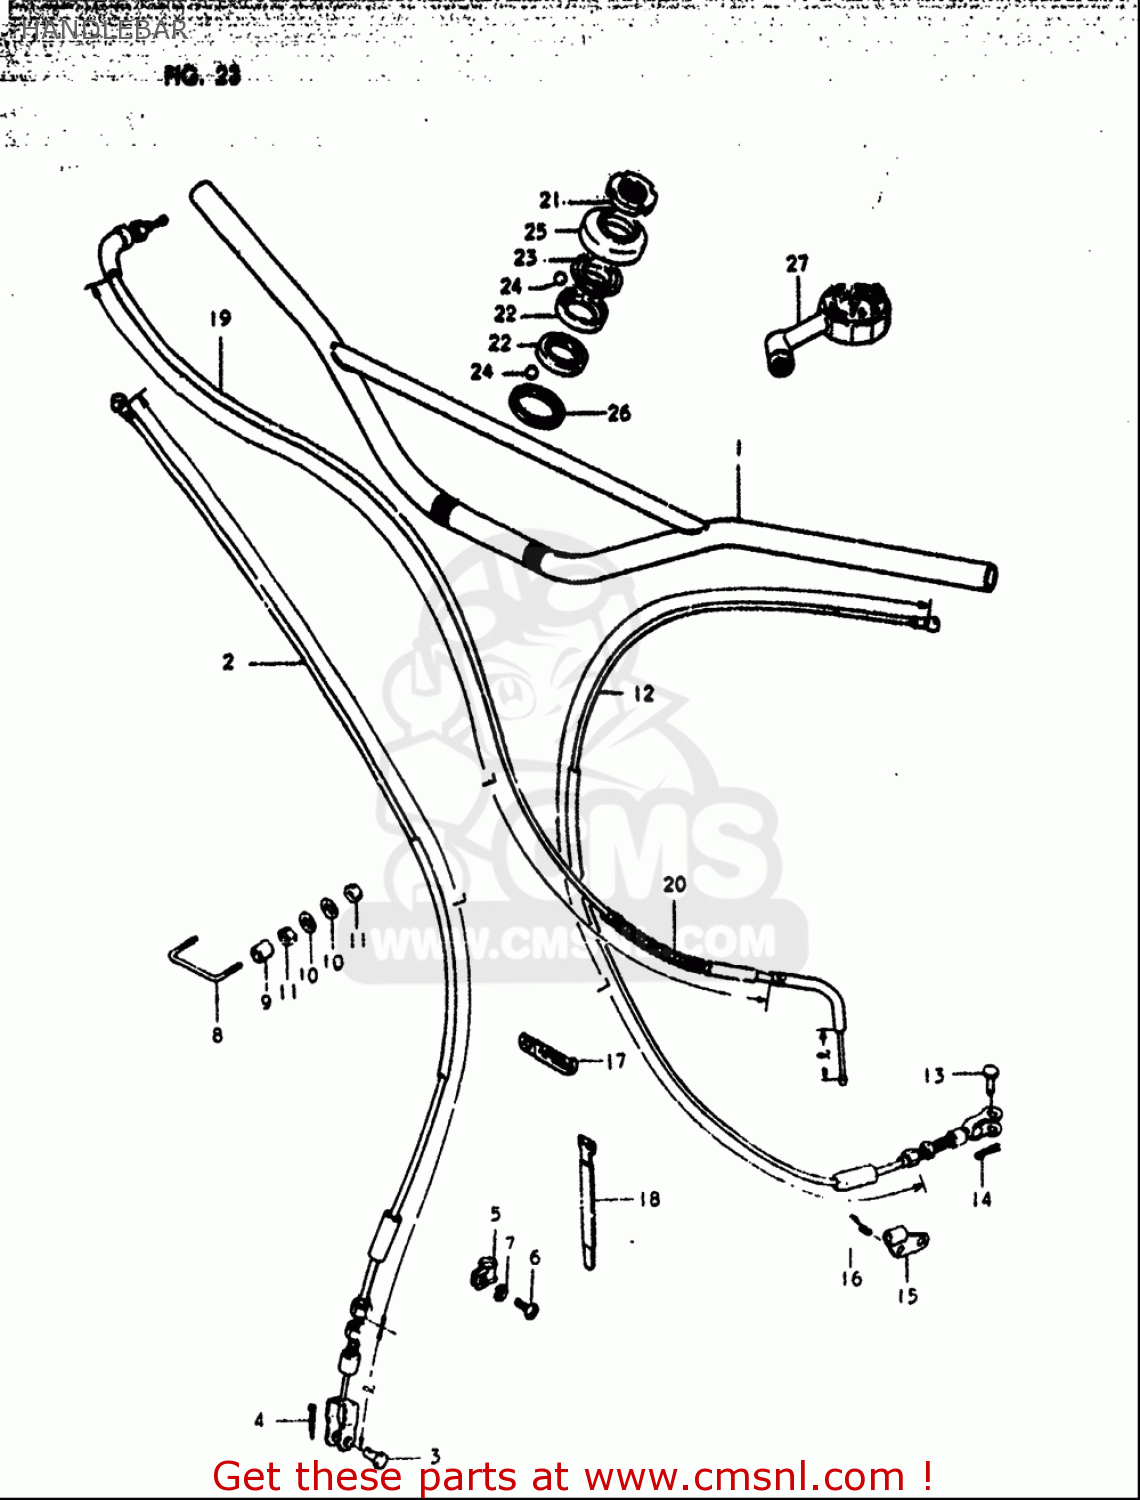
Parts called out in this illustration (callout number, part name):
2	CABLE,FR BRAKE
3	PIN(L:17.5)
4	PIN
5	GUIDE,CABLE
6	SCREW
7	WASHER,LOCK
10	WASHER
11	NUT
12	CABLE ASSY,CLUTCH
13	PIN(L:13)
14	PIN
15	STOPPER,CLUTCH CABLE
16	SCREW
17	CLAMP(L:65)
18	CLAMP
19	CABLE ASSY,THROTTLE
20	PROTECTOR,CABLE
21	NUT,STEERING STEM
22	RACE,STEERING INNER (SUJ)
23	LACE,STEERING OUTER UPR
24	BALL
25	SEAL,STEERING UPR DUST
26	DUST SEAL,STEERING HEAD
